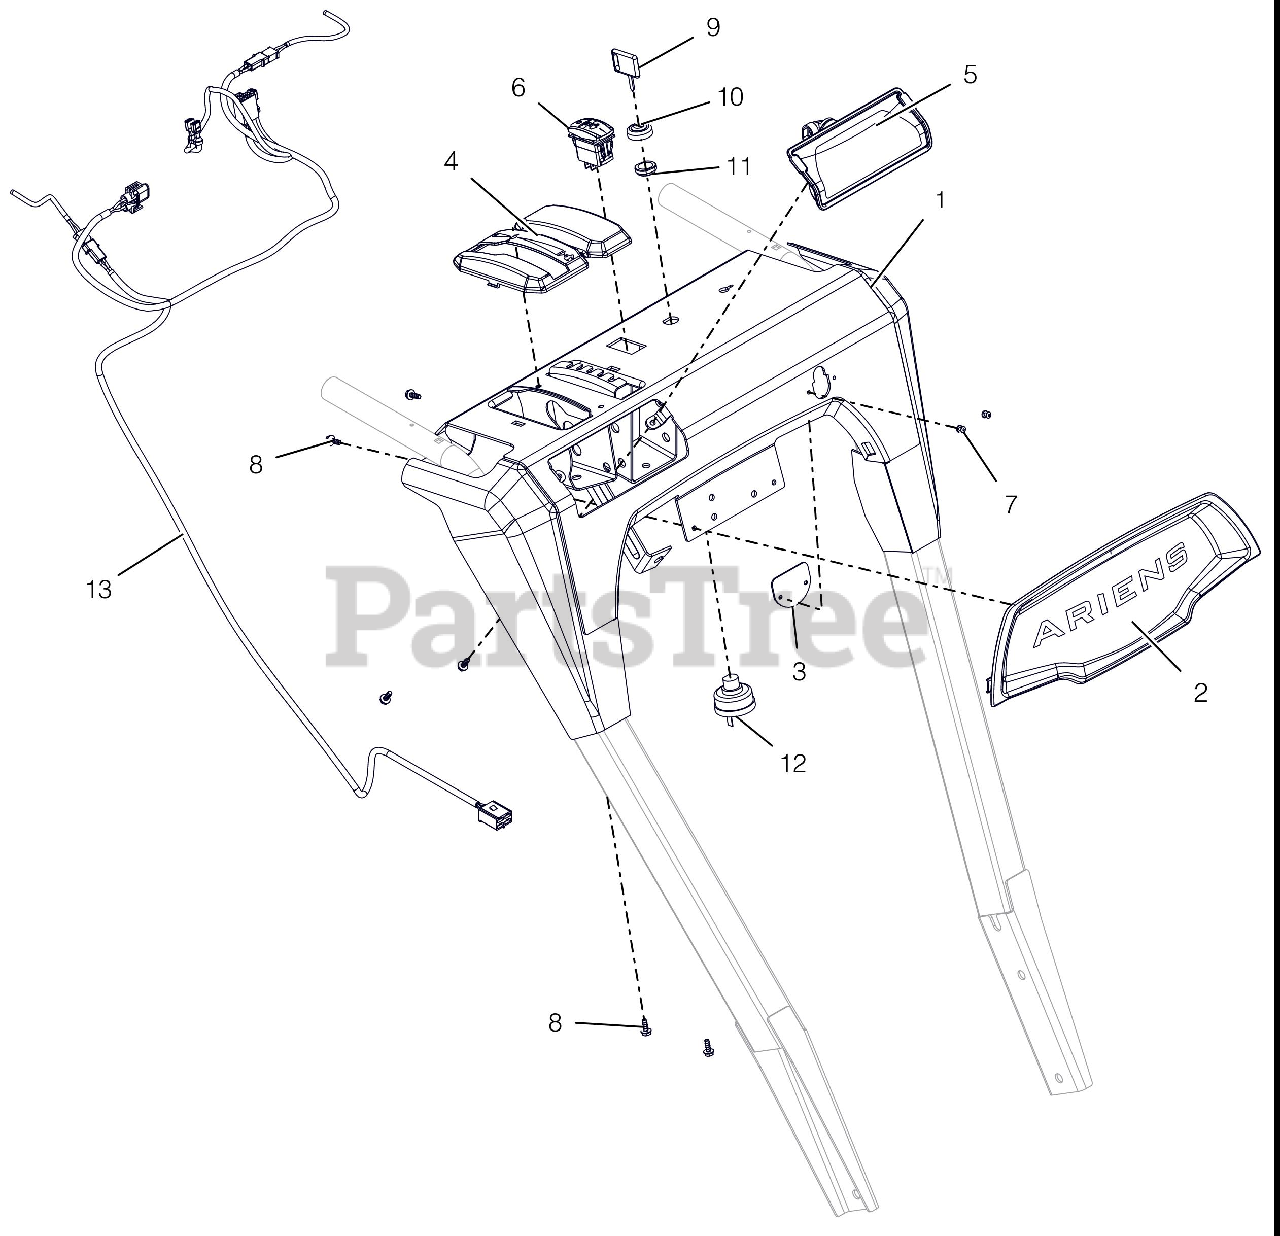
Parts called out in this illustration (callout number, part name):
1	PANEL, DASH - W/CTR DECAL(12V)
2	BEZEL, DASH - ARIENS LG DASH
3	COVER, DASH BRKT, BRUSH
4	BEZEL, SHIFT - HYDRO BRUSH
5	HEADLIGHT ASY, HOLO 15W 2 SHOT
6	SWITCH,ROCKER SPST-ON/OFF
7	RVT-POP #43 .125X.313 STL ZINC
8	SCR-TAP #10X.50 BOSS INDHXHD
9	KEY -W/CAP
10	CAP - IGNITION SWITCH
11	NUT-PANEL .625-32 GRECO
12	IGNITION SWITCH ASSEMBLY
13	HARNESS,ELEC - HANDLEBAR 12V
